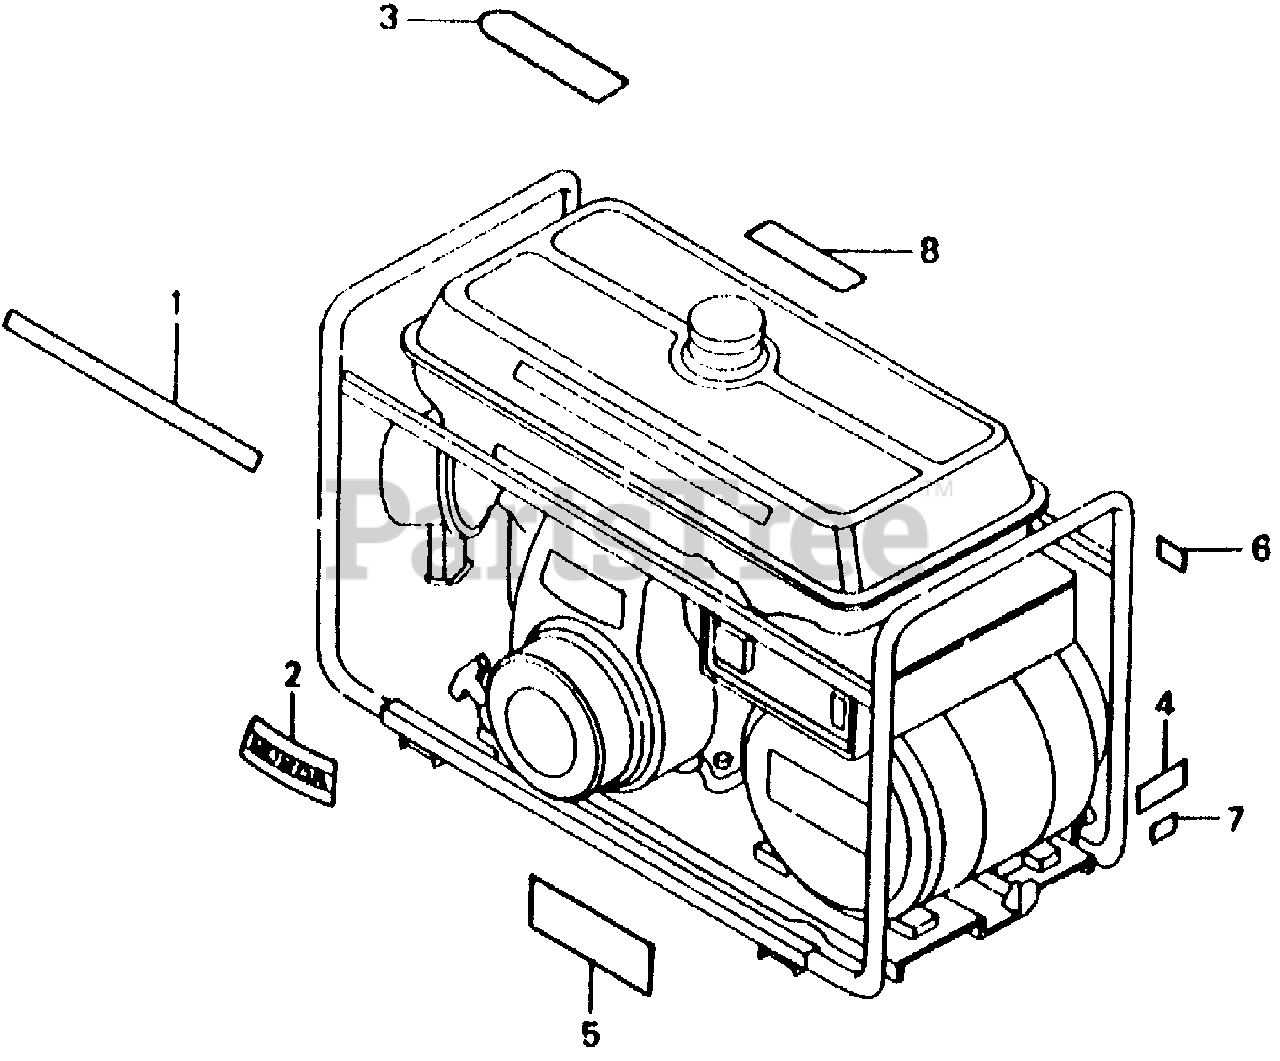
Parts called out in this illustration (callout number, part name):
3	MARK A, CAUTION
4	MARK C, CAUTION (NOT AVAILABLE)
5	PLATE, CAUTION
6	MARK, GROUND
7	MARK B, D.C. OUTPUT
8	MARK, CAUTION (CO)(ENGLISH/FRENCH)(SPANISH)
